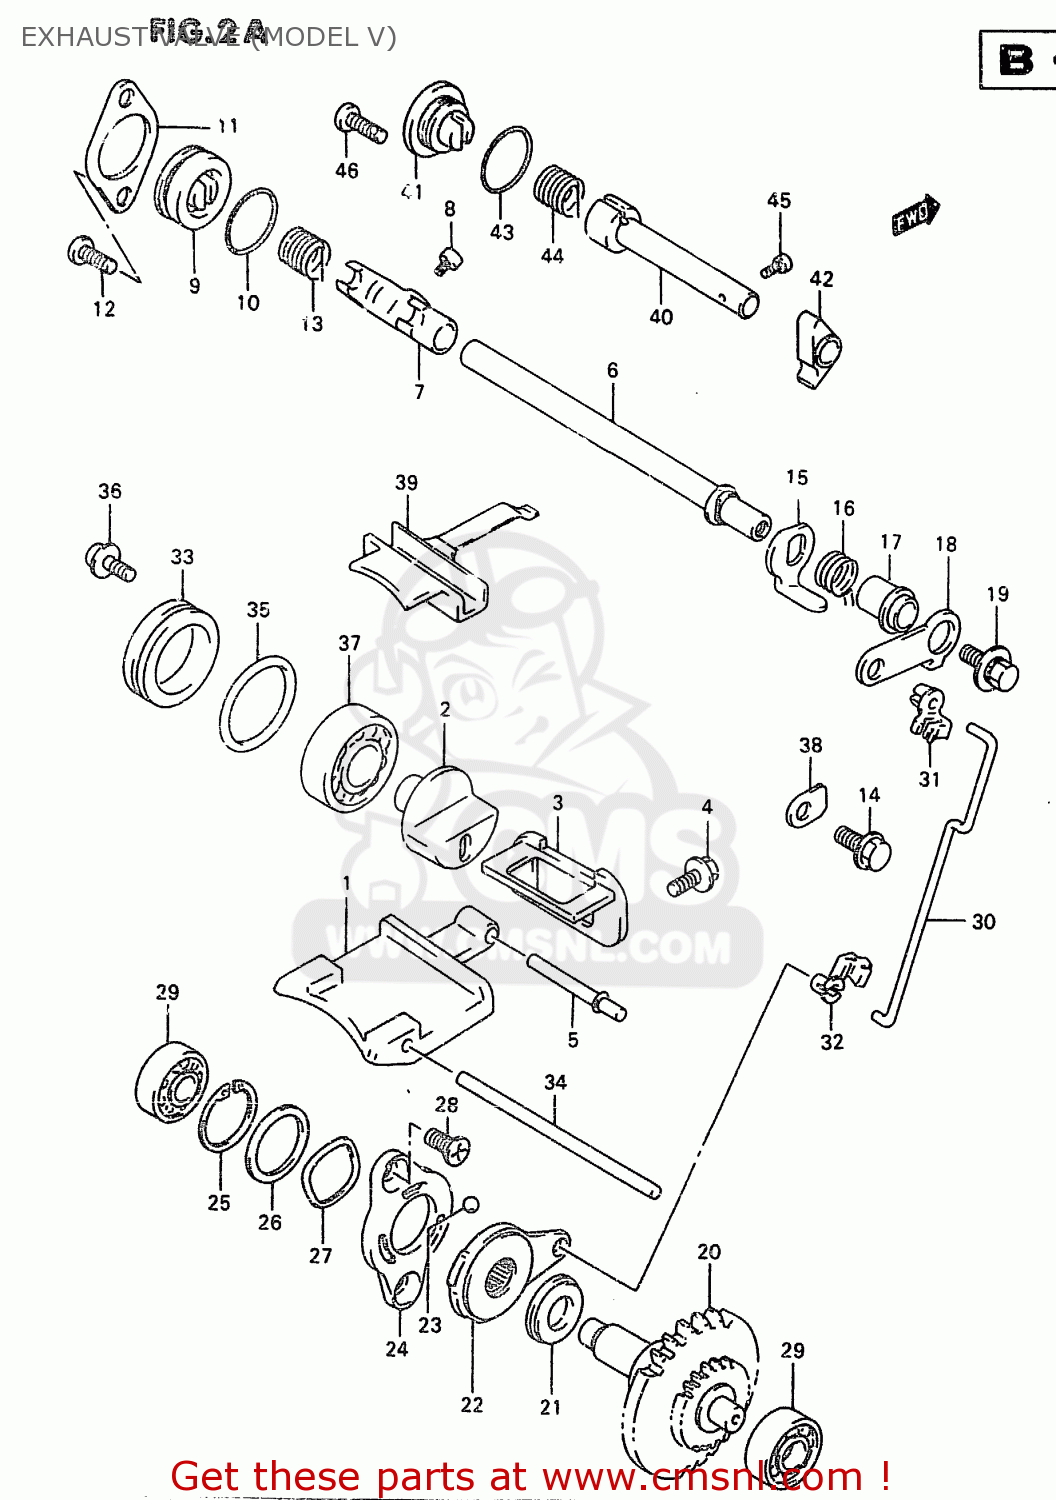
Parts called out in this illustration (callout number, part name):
1	VALVE,EXHAUST MAIN LOW
2	VALVE,EXHAUST SIDE
3	GUIDE,EXHAUST MAIN VALVE
4	SCREW 5X12
5	PIN,EXH MAIN VALVE & SPACER
6	SHAFT,EXHAUST VALVE
7	ARM,EXHAUST VALVE SHAFT
8	BOLT(4X8)
9	CAP,EXHAUST VALVE
10	O RING(D:1.9,ID:22.6)
11	RETAINER,EXHAUST VALVE
12	BOLT
13	SPRING
14	BOLT
15	LEVER,EXHAUST VALVE NO.2
16	SPRING
17	SPACER,EXHAUST VALVE
18	LEVER,EXHAUST VALVE NO.1
19	BOLT(5X12)
20	GOVERNOR ASSEMBLY,EXHAUST VALVE
21	BEARING(10X22X2.8)
22	ACTUATOR,EXHAUST VALVE
23	BALL
24	STARTER,EXHAUST VALVE ACTUATOR
25	CIRCLIP
26	SHIM(19.1X25X0.3)
27	WASHER
28	SCREW(5X10)
29	BEARING(8X22X7)
30	ROD,EXHAUST VALVE
31	BUSH,EXHAUST VALVE ROD NO.1
32	BUSH,EXHAUST VALVE ROD NO.2
33	CAP,EXHAUST SIDE VALVE
34	PIN
35	O RING(D:3.1,ID:26.4)
36	SCREW 5X12
37	BEARING
38	RETAINER
39	VALVE,EXHAUST MAIN,MIDDLE
40	SHAFT,CYLINDER COVER,N
41	CAP,CYLINDER COVER NO
42	ARM,CYLINDER COVER NO
43	O RING(D:1.9,ID:14.5)
44	SPRING,CYL COVER NO.2 SHAFT
45	BOLT(4X8)
46	SCREW 5X12
